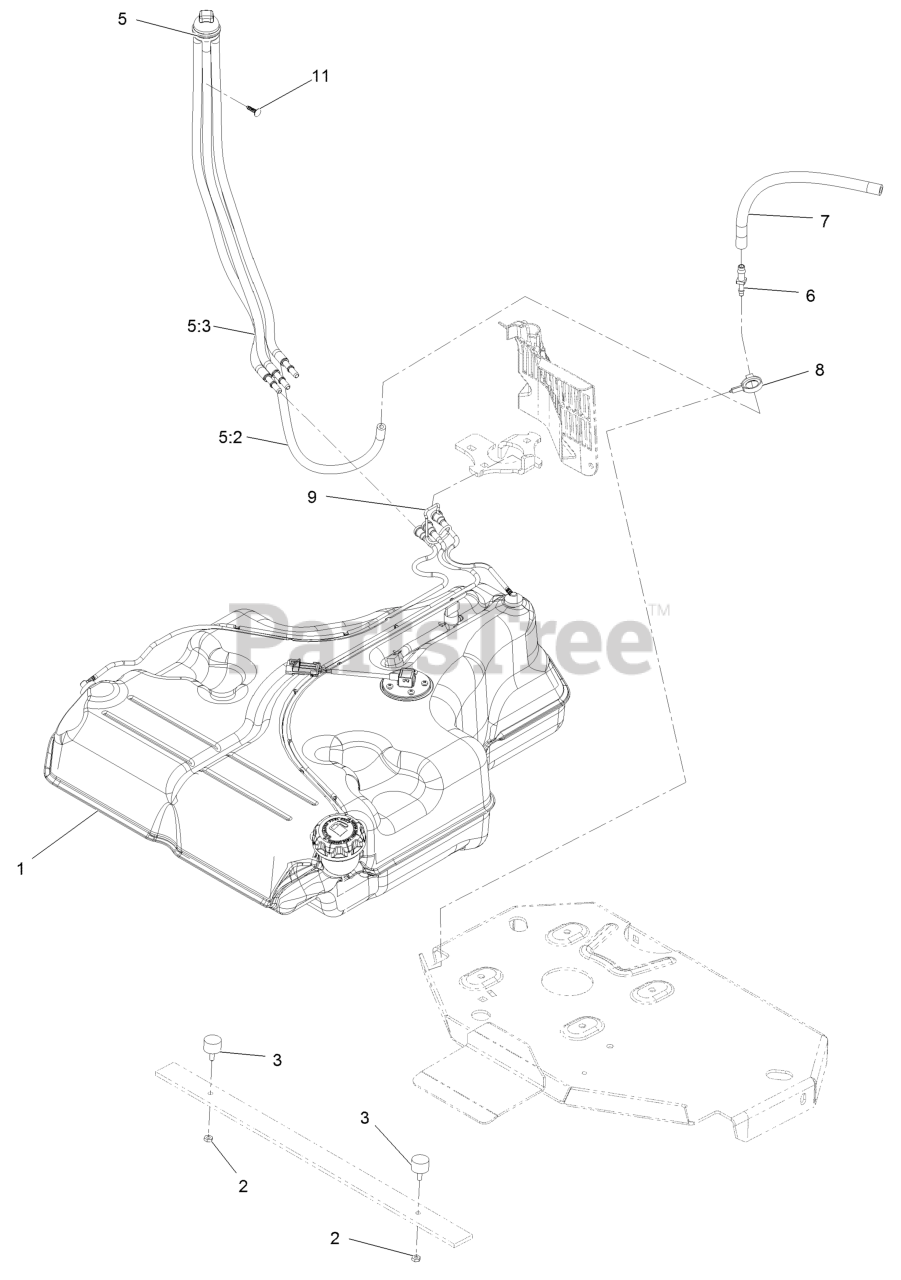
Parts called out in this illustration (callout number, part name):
2	NUT-JAM
5	FUEL MANIFOLD VENT ASM
5:2	HOSE-FUEL
5:3	HOSE-FUEL
6	FITTING-STRAIGHT
7	HOSE-FUEL
8	CLAMP-HOSE
9	RETAINER-LINE, VAPOR
11	PLUG-PLASTIC
